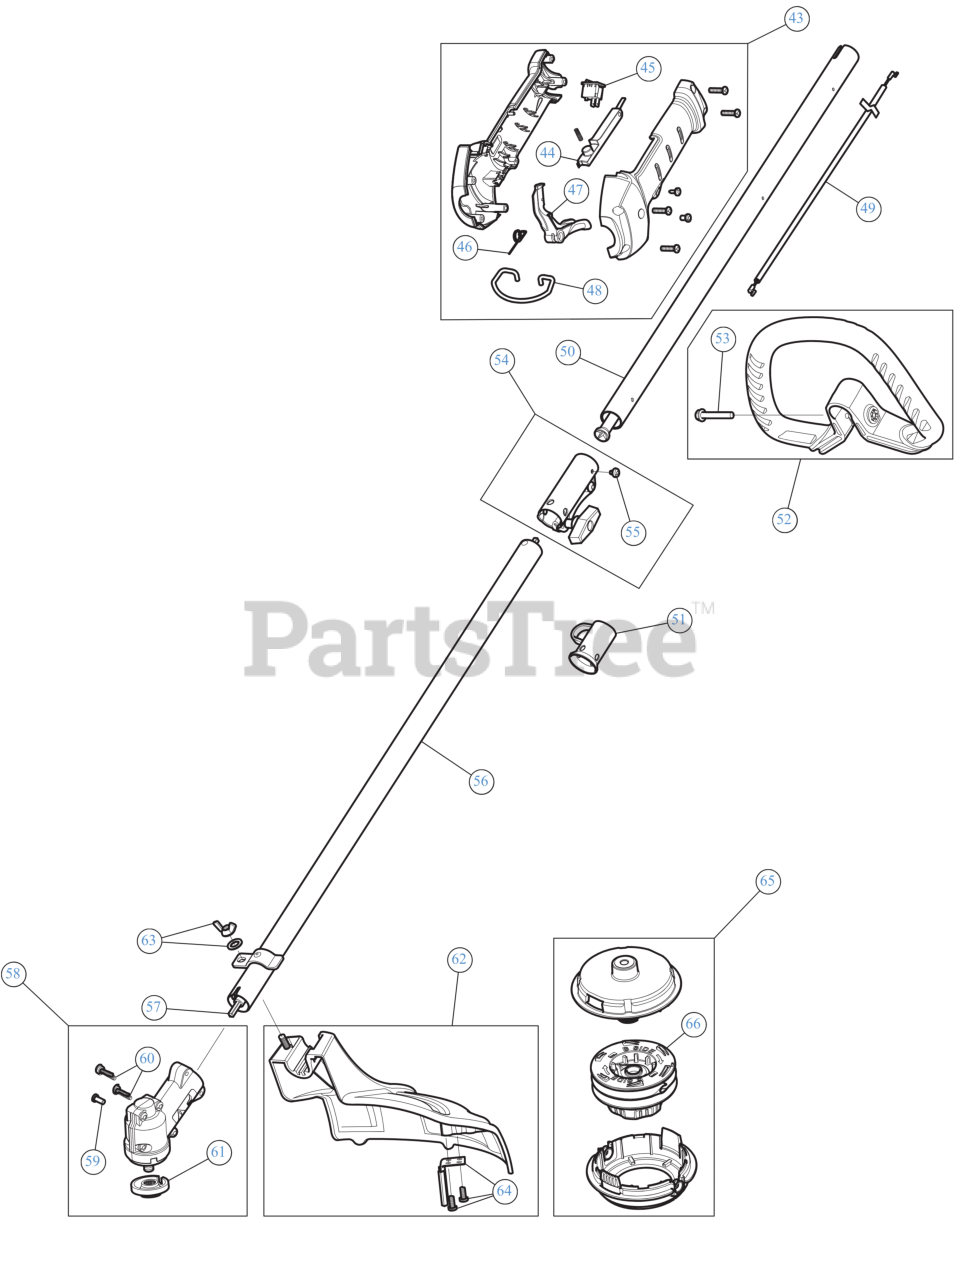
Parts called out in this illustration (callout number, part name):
43	THROTTLE GRIP ASM
44	LEVER LOCK OUT
45	SW, MOMENTARY ON/O
46	TRIGGER SPRING
47	THROTTLE TRIGGER
48	SHOULDER STRAP CLIP
49	THROTTLE CABLE
52	HANDLE ASSEMBLY
53	BOLT 1/4-20X1 1/2
54	SPLIT BOOM COUPLER KIT
55	SCREW, 10-32X.250 TA
56	BOOM ASSEMBLY LOWER
57	LOWER DRIVE SHAFT
58	GEARBOX LCBC
59	SCREW, 8-32 x .312 P
61	CUTTING HEAD SPACER
62	GUARD/BLADE ASM
63	BLADE GUARD MOUNTING HARDWARE
64	BLADE ASSEMBLY W/HDW
65	HEAD ASSEMBLY CNT/AF (LH) LRG
